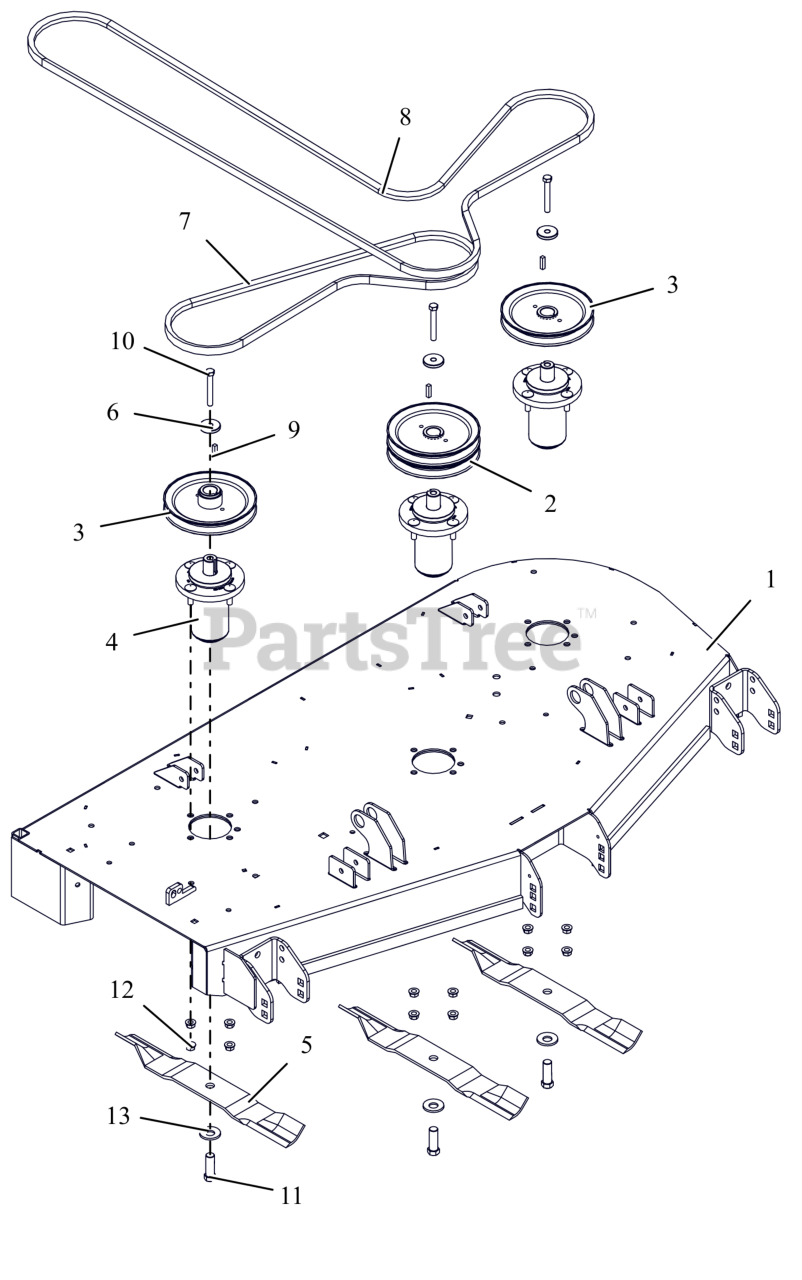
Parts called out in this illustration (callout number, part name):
1	KIT,DECK-52" W/DECALS - ARIENS
2	PULLEY, DOUBLE-1"ID X 6.75"OD
3	PULLEY, V-1" ID X 6.75" OD
4	ASM, MAINT FREE ALUM SPINDLE
5	BLADE, 18"
6	RETAINER, SHEAVE
7	V-BELT, B-COGGED
8	V-BELT, HB SECTION
9	KEY, SQ .25X.25X1.00 RC 40-50
10	BLT, HEX .38-16X2.75 G8 ZCC
11	BLT, HEX .62-18X1.75 G8 ZCC
12	NUT-LK-CTR-FLG .375-16 GF ZCC
13	WSHR-BLVL .669X1.535X.138
